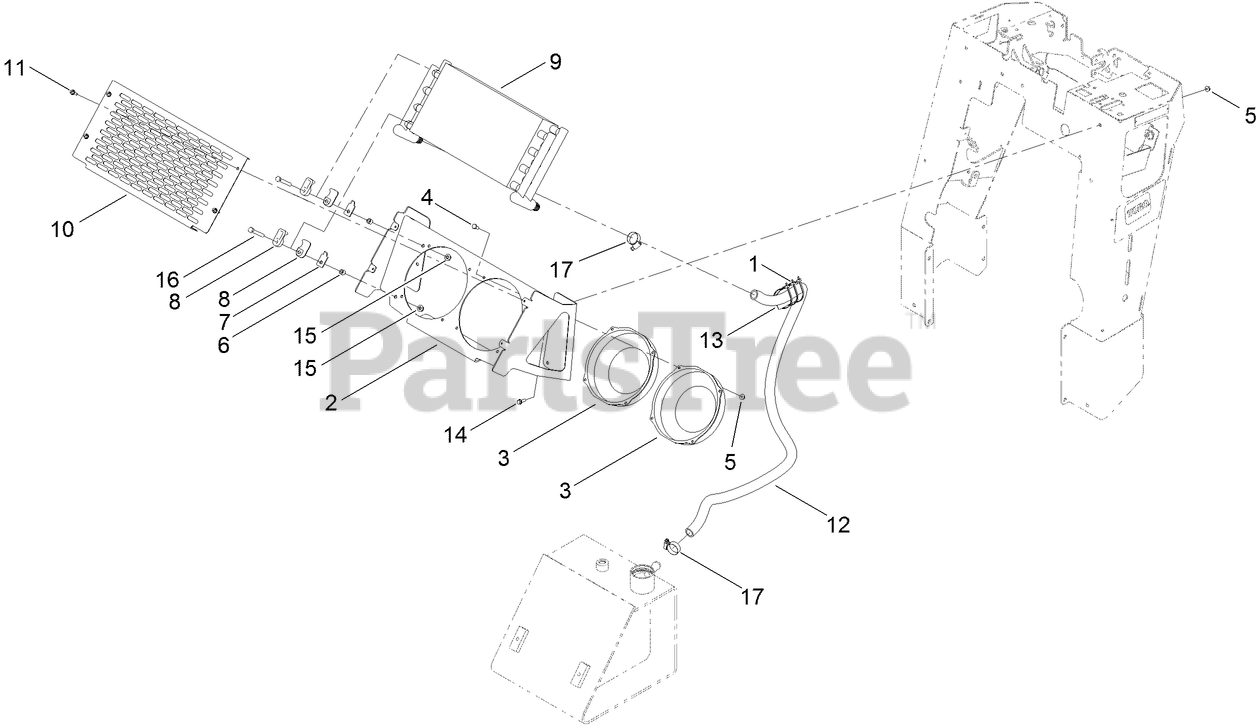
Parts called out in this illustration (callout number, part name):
1	TIE-CABLE
2	MOUNT-COOLER
4	SCREW-HH
5	NUT-HF
6	Spacer-Tube
7	PLATE-SUPPORT, CLAMP
9	COOLER-OIL
10	COVER-COOLER
11	SCREW-HWH
12	HOSE-RETURN
13	PROTECTOR-HOSE
14	SCREW-HHF
15	NUT-HF, NI
16	SCREW-HH
17	CLAMP-HOSE
